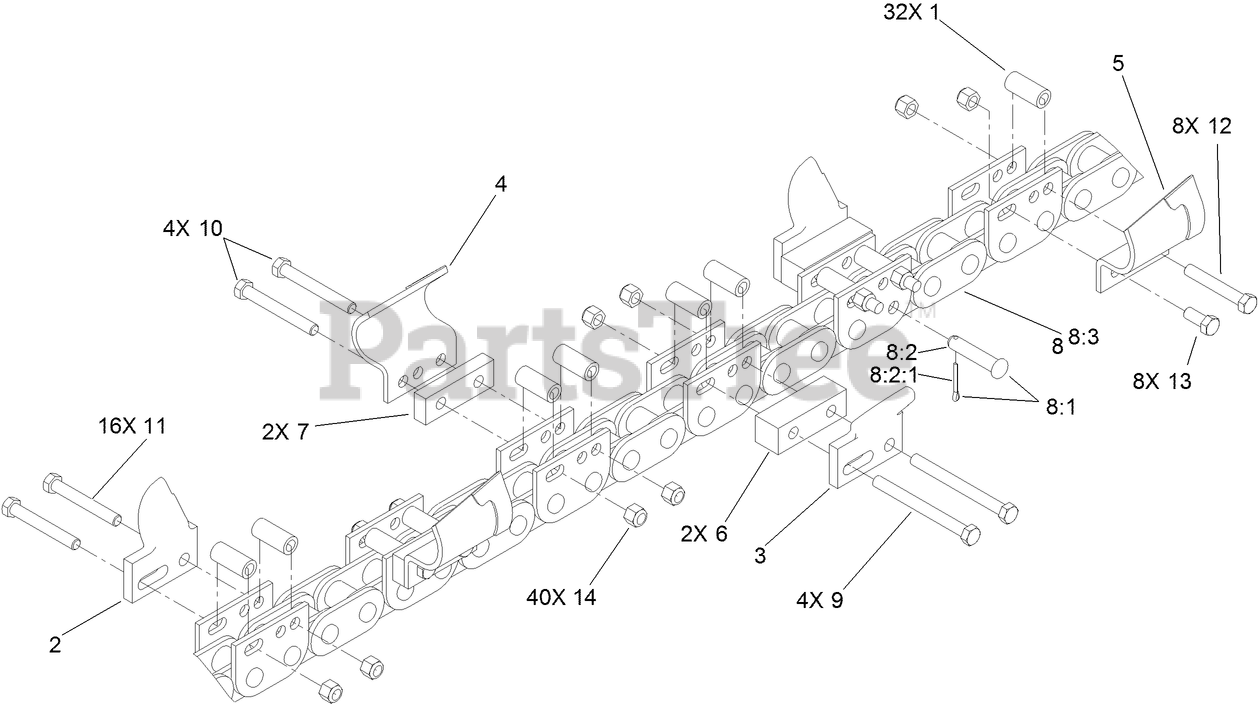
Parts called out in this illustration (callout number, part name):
1	SPACER-TUBE
2	TOOTH- ROCK, LH
3	TOOTH-ROCK, RH
4	TOOTH-SOIL, LH
5	TOOTH-SOIL, RH
6	SPACER-CUT, 6 INCH
7	SPACER-CUT, 5 INCH
8	CHAIN-BARE, 20 STATION
8:1	PIN-CONNECTING
8:2	PIN-CONNECTING (61MM)
8:2:1	PIN-COTTER
8:3	LINK REPAIR KIT
9	SCREW-HH
10	SCREW-HH
11	SCREW-HH
12	SCREW-HH
14	NUT-HEX
